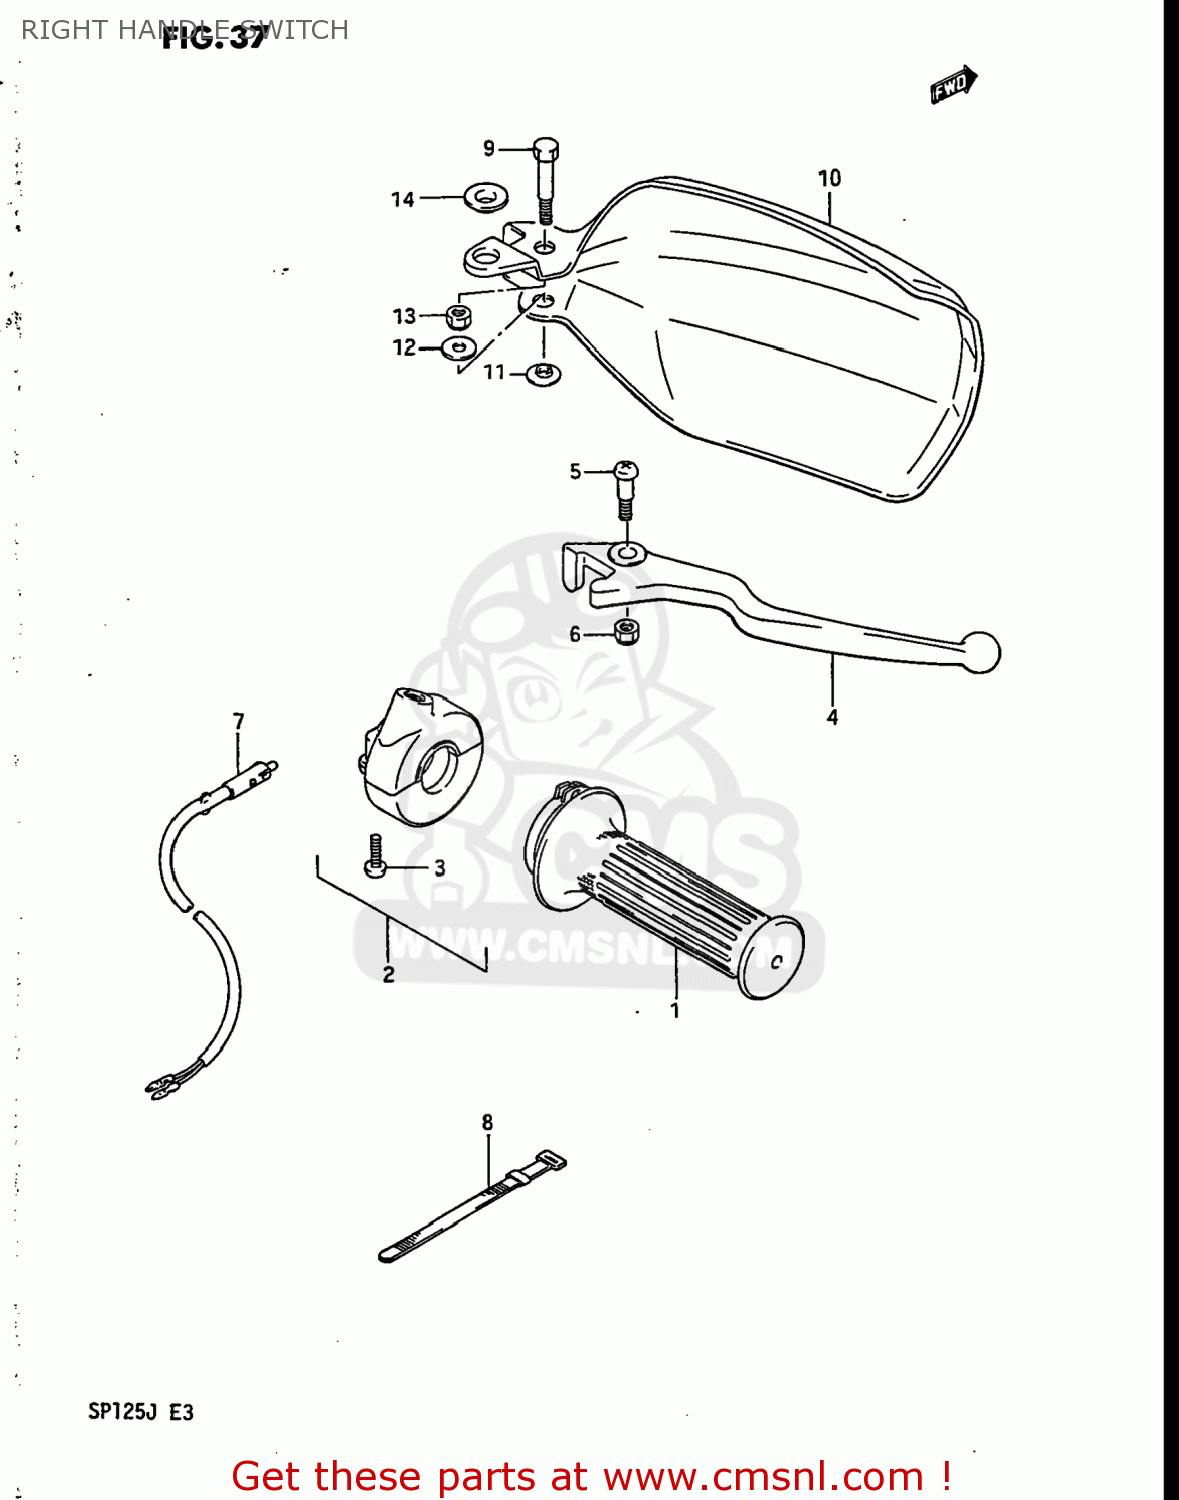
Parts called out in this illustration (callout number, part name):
1	GRIP,THROTTLE
2	CASE ASSY,THROTTLE
3	SCREW 5X20
4	LEVER,BRAKE
5	SCREW
6	NUT
7	SWITCH ASSY,STOP
8	CLAMP(L:120)
9	BOLT,LEVER PIVOT
10	COVER,KNUCKLE,RIGHT
11	WASHER
12	WASHER(6.5X16X1.2)
13	NUT 6MM
14	WASHER
